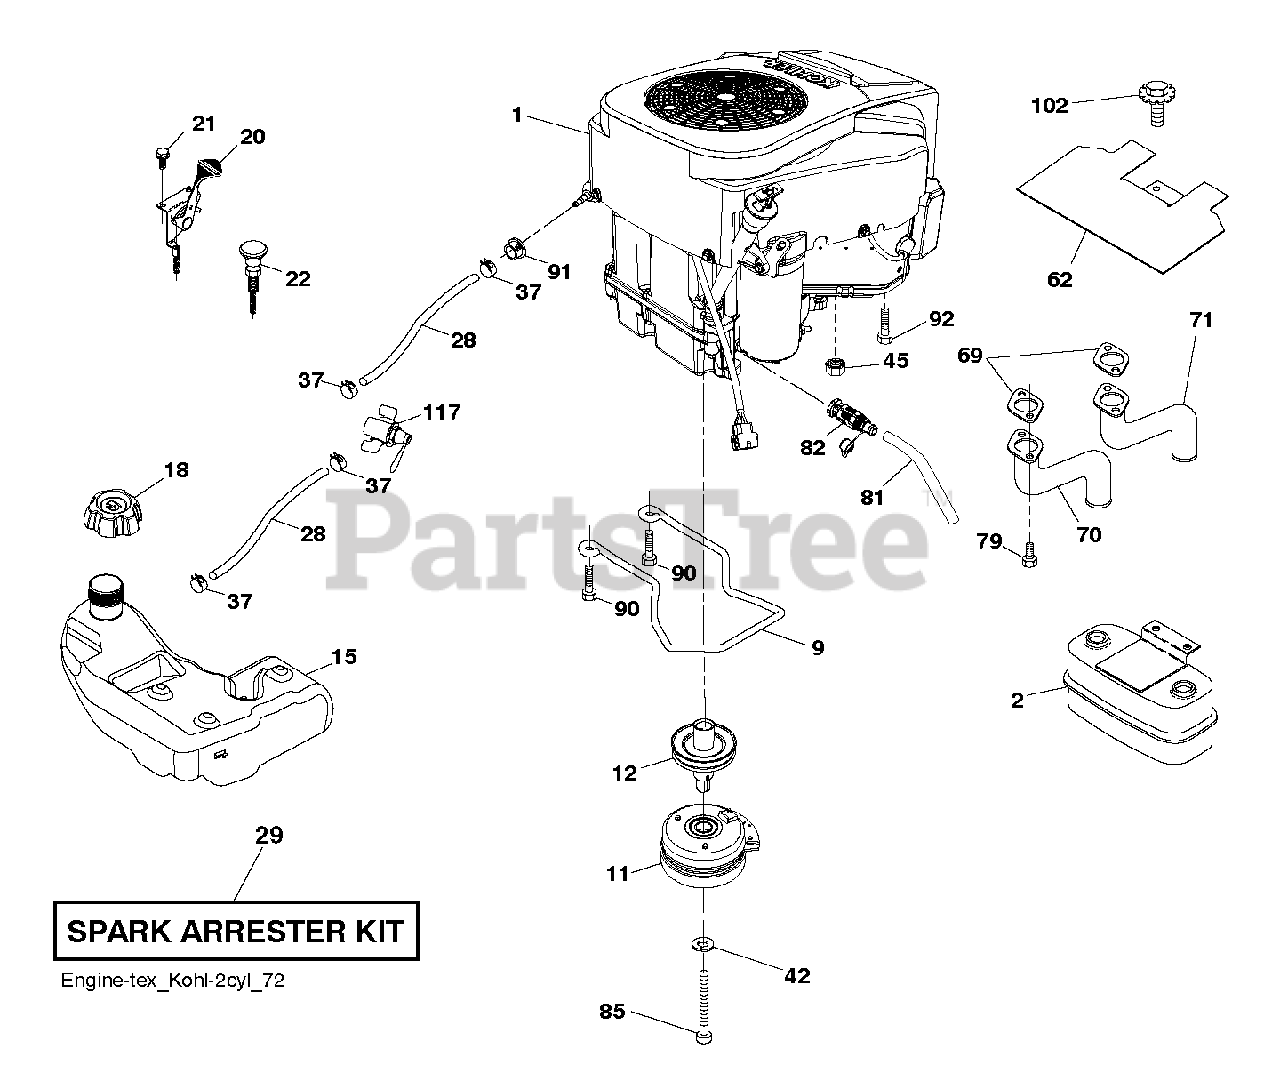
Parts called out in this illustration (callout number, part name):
2	MUFFLER.ASM.TWN.EXTNDED.DFLCTR
9	KEEPER.BELT.ENG.4.25"2.BLT.431
11	CLUTCH. 5.0 PD. 2.5 OFFSET
12	PULLEY.EXTENDED.SHAFT.GROUND
18	CAP.ASSY.FUEL.3".N-EPA.GRY.498
20	THROTTLE CONTROL
21	SCREW.#10 X 0.750.BOS
22	CONTROL.CHOKE.ERGO.PUSH-IN.BLA
28	HOSE.14.FUEL.LINE.60.
29	KIT.SPARK ARRESTOR 794945 B&S
37	HOSE CLAMP
42	WASHER 7/16 LOCK
45	NUT
62	SHIELD.HEAT.MUFFLER
69	GASKET.EXHAUST.KOHL.CV18-CV26
70	PIPE.EXHAUST.LH.CV18/20
71	PIPE.EXHAUST.RH.CV18/20
79	SCREW.SOCKET HD.5/16-1
81	TUBE, DRAIN OIL ASM.
82	VALUE.OIL.DRAIN
85	BOLT.HEX.7/16-20X5.GR5.GREEN
90	SCREW 3/8-16X1
91	BUSHING.1.375OD
92	SCREW 3/8-16X1
102	SCREW
117	VALVE FUEL RESERVE
